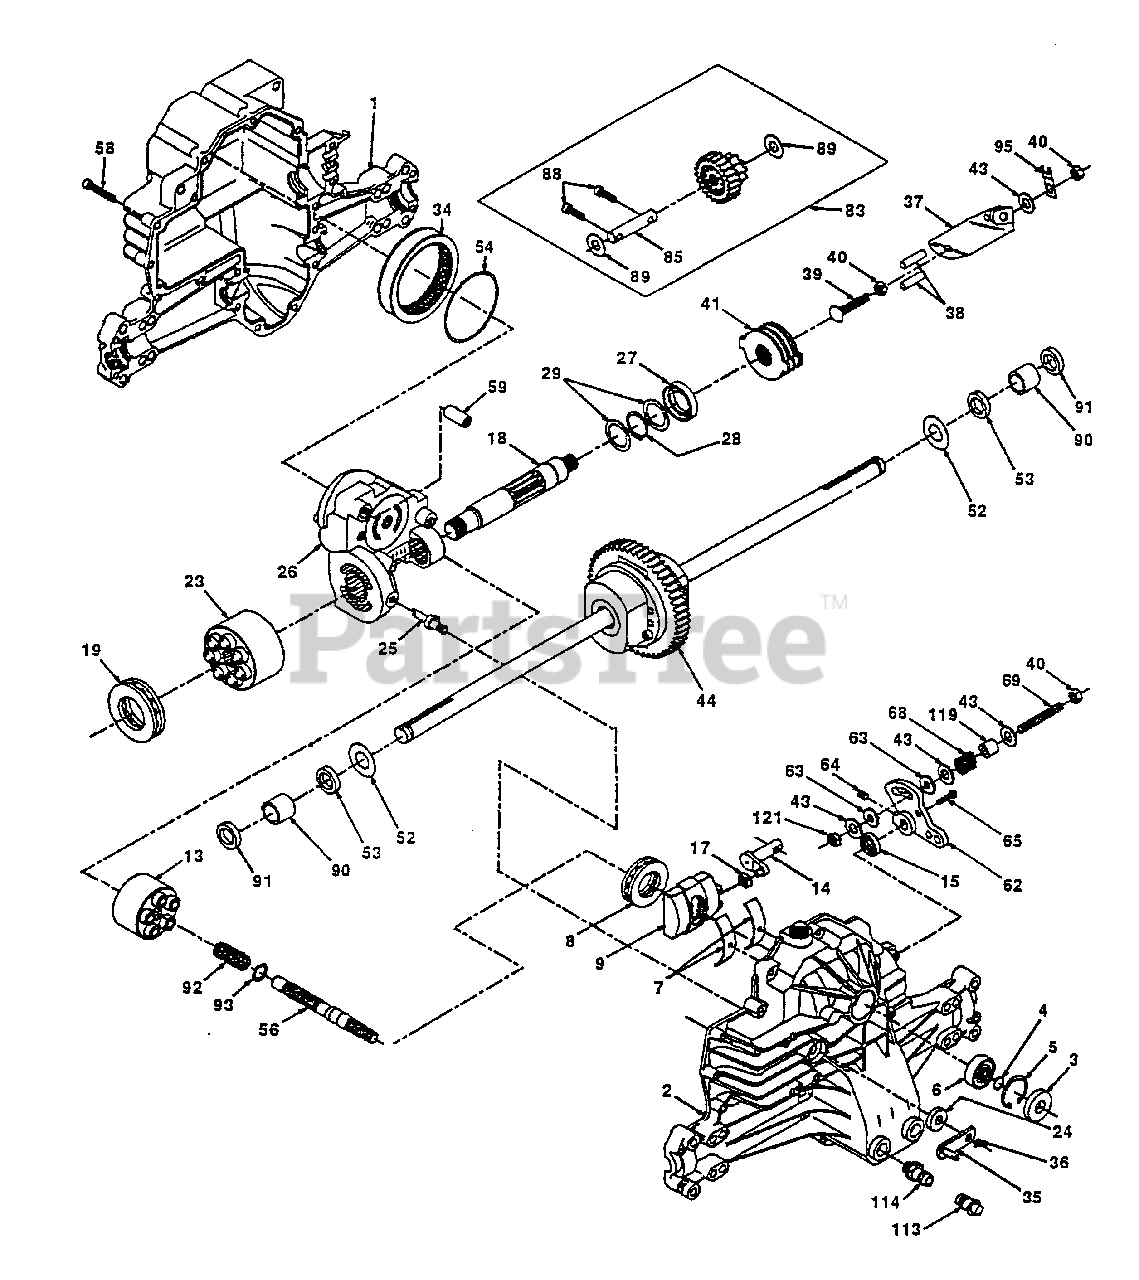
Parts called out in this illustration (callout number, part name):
1	Housing, Lower
2	Assembly, Upper Housing
3	Seal, Lip
4	Ring, Wire Retaining
5	Ring, Retaining
6	Bearing, Shaft Ball
7	Bearing, Cradle
8	Bearing, Thrust 30 x 52 x 13
9	Swashplate, Variable
13	Block, Cylinder Assembly
14	Arm, Trunnion
15	Seal, Lip
17	Guide, Slot
18	Shaft, Motor
19	Bearing, Thrust 42 x 68 x 16
23	Block, Cylinder Assembly
24	Seal, Lip 10 x 25 x 7
25	Actuator, Bypass
26	Center Section Assembly Kit
27	Seal, Lip 26 x 42 x 8
28	Ring, Retaining
29	Washer 26 x 35 x 1
34	Oil Filter Element
35	Arm, Bypass
36	Ring, Retaining
37	Arm, Actuating
38	Pin, Actuating
39	Bolt 5/16-24 x 1-3/4
40	Locknut, Hex 5/16-24 UNJC
41	Brake Rotor/Stator Kit
43	Washer 7/16 x 7/8 x .060
44	Differential Assembly
52	Washer 3/4 x 1.5 x .03
53	Seal .75 x 1.25 x .250
54	O-Ring .103 x 2.987 ID
56	Shaft, Input
58	Bolt 1/4-20 x 1.38
59	Pin .5 OD x .43 ID x .750
62	Arm, Control
63	Puck, Dampener
64	Set Screw
65	Bolt #8-32 x .875
68	Spring
69	Socket Set Screw
83	Jack Shaft Assembly
85	Jack Shaft
88	Capscrew
89	Washer
90	Sleeve Bearing
91	Seal, Wiper
92	Spring, Block
93	Washer, Block Thrust
95	Strap, Locking
113	Cap, Vent Assembly
114	Fitting, O-Ring Assembly
119	Spacer
121	Jam Nut 5/16-24
